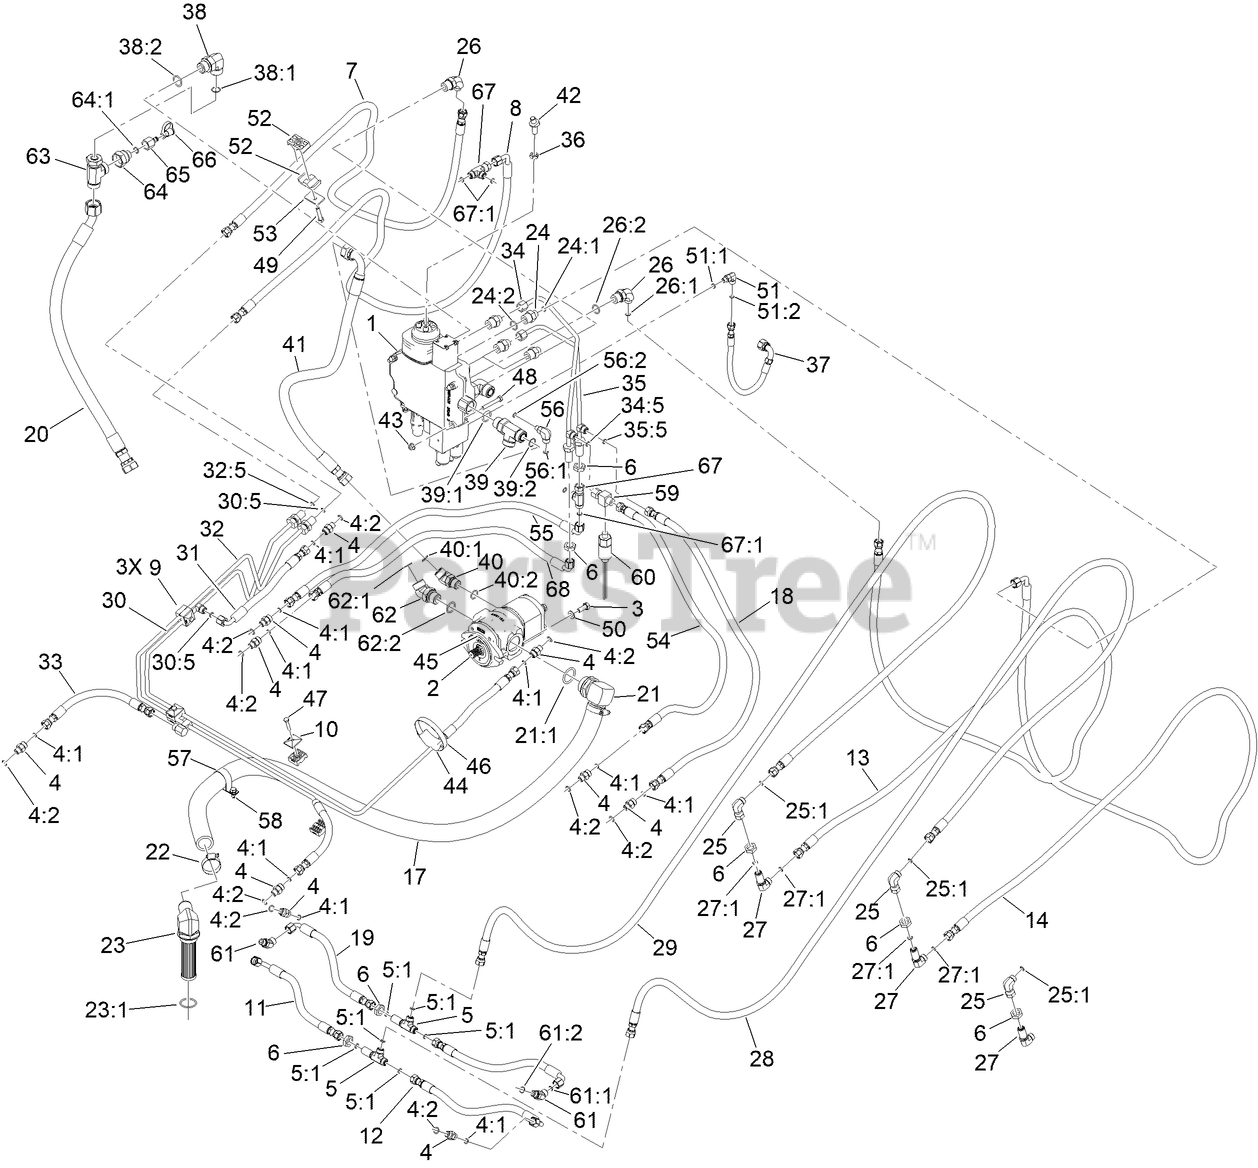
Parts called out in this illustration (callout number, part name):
1	LIFT VALVE ASM
2	GEAR PUMP ASM
3	SCREW-HH
4	FITTING-STRAIGHT
4:1	O-RING
4:2	O-RING
5	FITTING-TEE, BULKHEAD
5:1	O-RING
6	NUT-LOCK
7	HYD HOSE ASM
8	HYD HOSE ASM
9	CLAMP-HOSE
10	PLATE-CLAMP, RETAINER
11	HYD HOSE ASM
12	HYD HOSE ASM
13	HYD HOSE ASM
14	HYD HOSE ASM
18	HYD HOSE ASM
19	HYD HOSE ASM
20	HYD HOSE ASM
21	FITTING-HYD 90 SPCL
21:1	O-RING
23	STRAINER FITTING ASM
23:1	O-RING
24	FITTING-STR
24:1	O-RING
24:2	O-RING
25	FITTING-HYD, 90 DEG
25:1	O-RING
26	FITTING-ELBOW 90
26:1	O-RING
26:2	O-RING
27	UNION-BULKHEAD
27:1	O-RING
28	HYD HOSE ASM
29	HYD HOSE ASM
30	HYD TUBE ASM
30:5	O-RING
31	HYD HOSE ASM
32	HYD TUBE ASM
32:5	O-RING
33	HYD HOSE ASM
34	HYD TUBE ASM
34:5	O-RING
35	HYD TUBE ASM
35:5	O-RING
37	HYD HOSE ASM
38	FITTING-ELBOW-90
38:1	O-RING
38:2	O-RING
39	FITTING-TEE
39:1	O-RING
39:2	O-RING
40	FITTING-HYD, 45 DEG
40:1	O-RING
40:2	O-RING
41	HYD HOSE ASM
42	SHAFT-CONTROL
43	NUT-HF, NI
44	BLOCK-HARDLINE
45	O-RING
46	CLAMP-BAND/SCREW
47	SCREW-HH
48	SCREW-HH
49	SCREW-HH
50	WASHER-FLAT
51	FITTING-ELBOW, 90 DEG
51:1	O-RING
51:2	O-RING
52	CLAMP-TUBE
53	COVERPLATE
54	HYD HOSE ASM
55	HYD HOSE ASM
56	FITTING-ELBOW, 90 DEG
56:1	O-RING
56:2	O-RING
57	CLAMP-R
58	SCREW-HWH
59	FITTING-HYD, SPECIAL
60	SWITCH-PRESSURE,
61	FITTING-ELBOW, 45 DEG
61:1	O-RING
61:2	O-RING
62	FITTING-45 DEG
62:1	O-RING
62:2	O-RING
63	FITTING-HYD
64	FITTING-STRAIGHT
64:1	O-RING
65	FITTING
66	CAP-DUST
67	FITTING-TEE, SWIVEL NUT
67:1	O-RING
68	HYD HOSE ASM
